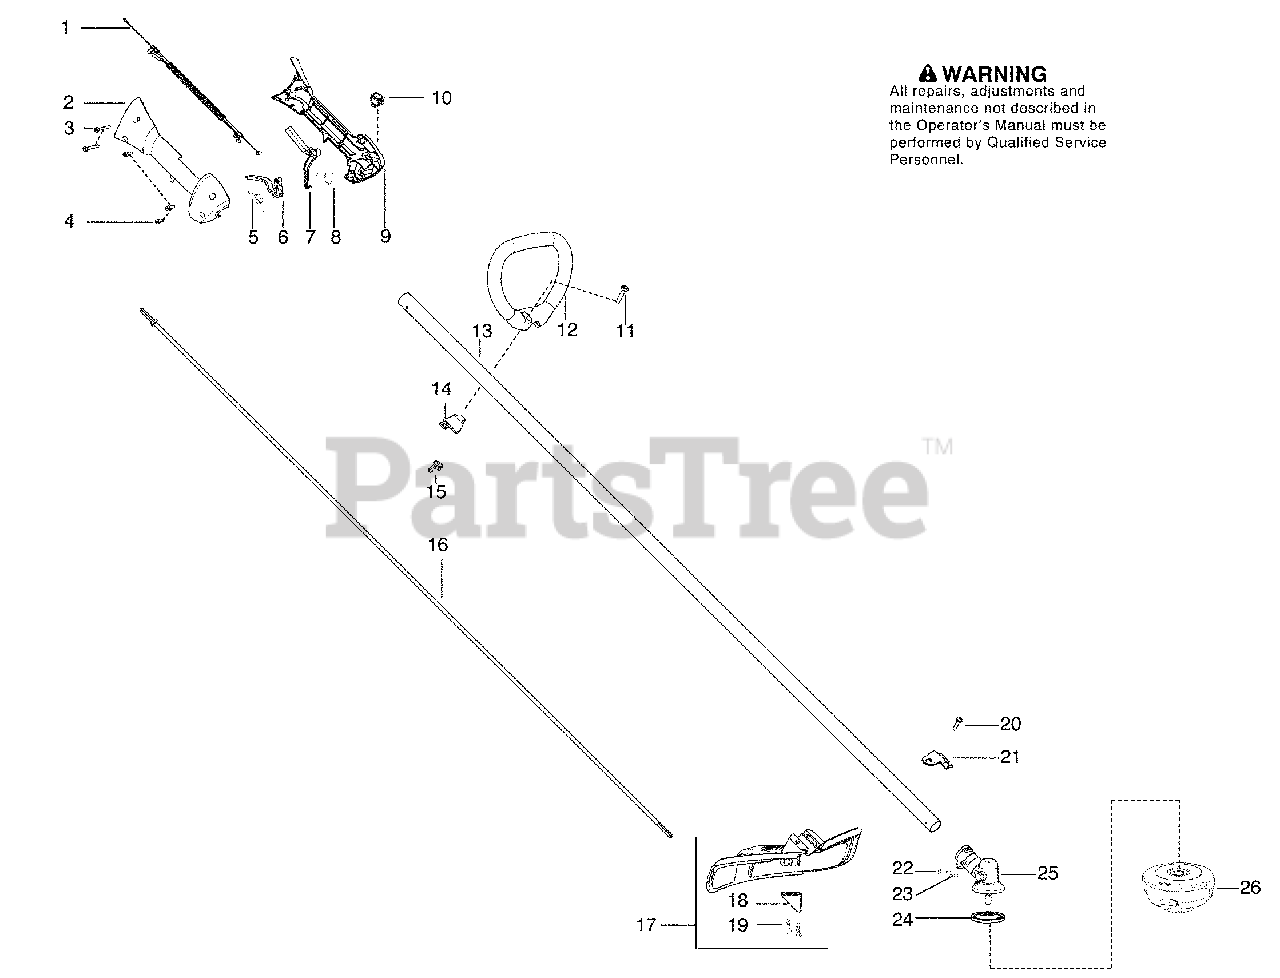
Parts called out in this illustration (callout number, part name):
1	Assy-Cable/Wire Harness
2	Housing-Throttle (RH)
5	Spring-Trigger
7	Lockout-Throttle
8	Spring-Lockout
9	Housing-Throttle (LH)
10	Kit-Switch
12	Handle-Assist
13	Kit-Driveshaft SST
14	Clamp-Handle
15	Wingnut
16	Flex shaft
17	Kit-Shield
18	Limiter-Line
21	Bracket-Shield
24	Driver Disc
25	Assy-Gearbox
26	Assy-T25 Cutting Head
